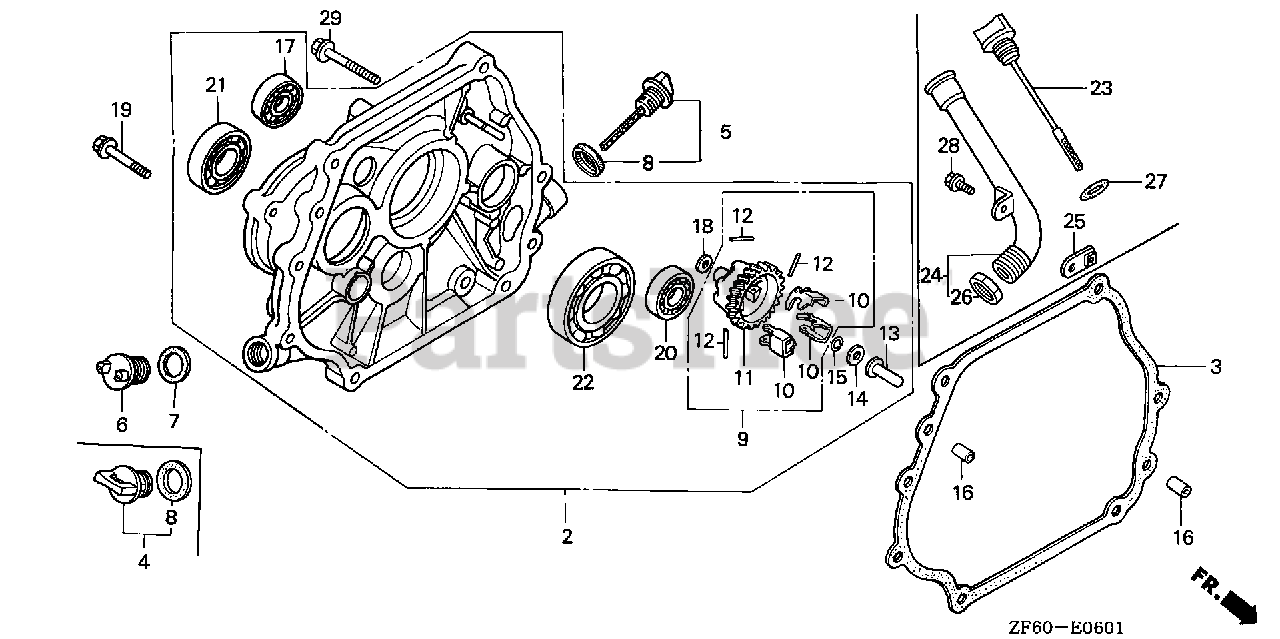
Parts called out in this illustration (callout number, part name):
2	COVER ASSY., CRANKCASE
3	GASKET, CASE COVER
4	CAP ASSY., OIL FILLER
5	CAP ASSY., OIL FILLER
6	CAP, OIL FILLER
7	GASKET, OIL FILLER CAP
8	GASKET, OIL FILLER CAP
9	GOVERNOR ASSY.
10	WEIGHT, GOVERNOR
11	HOLDER, GOVERNOR WEIGHT
12	PIN, GOVERNOR WEIGHT
13	SLIDER, GOVERNOR
14	WASHER (6X16)
15	CLIP, GOVERNOR HOLDER
16	PIN, DOWEL (8X12)
17	BEARING, RADIAL BALL (6202) (NTN)
18	WASHER, PLAIN (6MM)
19	BOLT, FLANGE (8X40)
20	BEARING, RADIAL BALL (6202)
21	BEARING, RADIAL BALL (6204) (TOYO)
22	BEARING, RADIAL BALL (6207)
